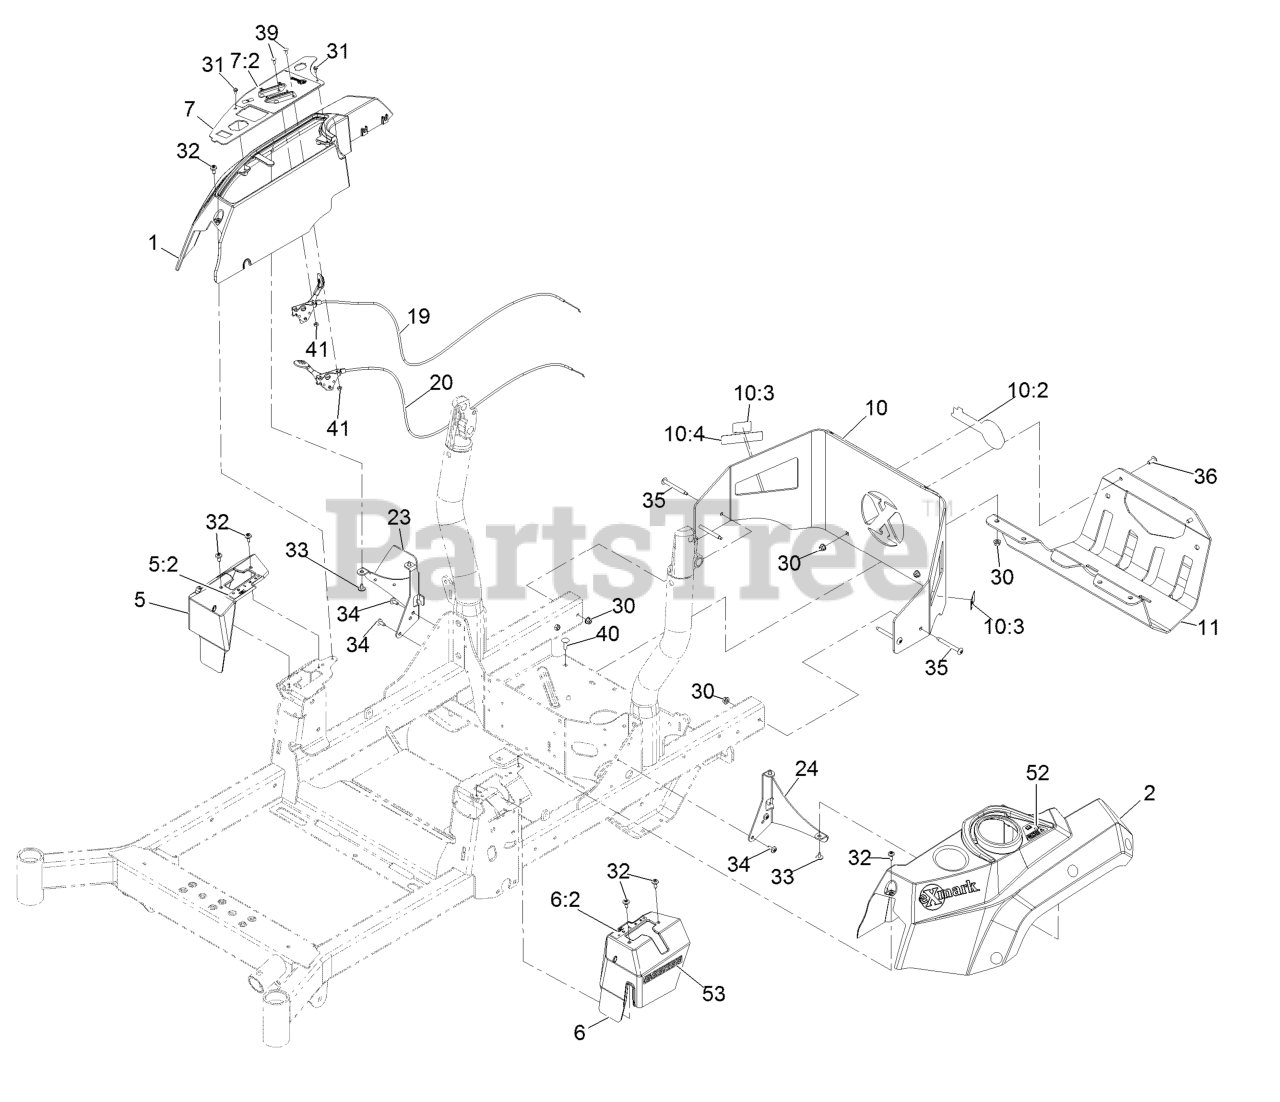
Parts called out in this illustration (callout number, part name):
1	Console, RH
2	Console, LH
5	Cover-Control, Motion (RH)
5:2	Decal-Control, Motion (RH)
6	Cover-Control, Motion (LH)
6:2	Decal-Control, Motion (LH)
7	Ctrl Panel ASM W/Decal
7:2	Decal-Control Panel
10	Rear Guard ASM
10:2	Decal-Exmark Logo
10:3	Decal-Warning
10:4	Decal-Arrester, Spark
11	Guard-Muffler
19	Cable-Control, Choke
20	Cable-Control, Throttle
23	Support-Console, RH
24	Bracket-Console, LH
30	Nut-Nyloc 5/16-18 Flg
31	Screw-HWH #10-14 X 1/2
32	Screw-1/4-20 X 1/2 Tf Torx Plus
33	Screw-HWH #10-14 X 1/2 Torx
34	Screw-1/4-20 X .65 Torx Plus
35	Screw-Truss HD 5/16-18 X 2 3/4 Torx Plus
36	Screw-TrussHD 5/16-18 X 3/4 Torx Plus
39	Bolt-Carriage #10-24 X 1/2
40	Bolt-Carriage 5/16-18 X 1 Sp
41	Nut-Nyloc #10-24
52	Decal-Fill, Fuel
53	Decal-E-Series
